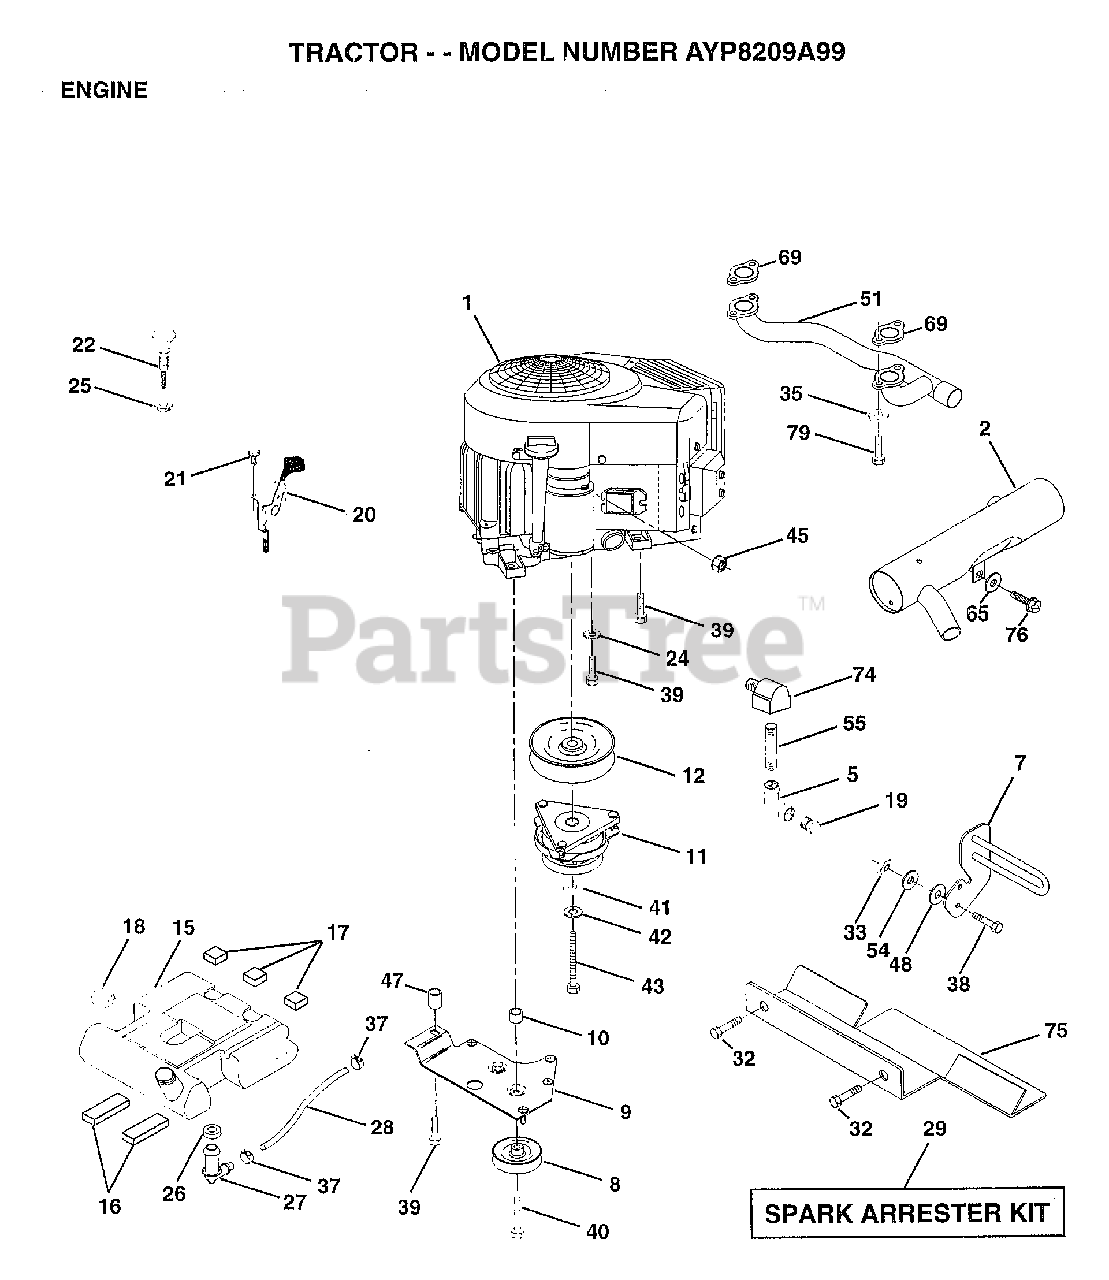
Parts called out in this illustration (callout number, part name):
2	MUFFLER.SIDE.VGT
5	ELBOW
7	GUARD.MUFFLER.ASM
9	KEEPER ASM BELT
10	BUSHING.
12	PULLEY.ENG.CLUTCH
15	TANK FUEL REAR
16	PAD IDLER TI
17	PAD-SPACER LT
18	CAP ASM FUEL
19	PLUG T
20	CONTROL.TRTL.37
21	SCREW LT
22	CHOKE CONTROL
24	LOCKWASHER
25	"NUT,KEPS 3/8-24IM"
26	BUSHING OUTLET T
27	STEM.TANK.FUEL
29	SPARK ARREST KIT
32	SCREW LT
33	NUT
35	LOCKWASHER
37	HOSE CLAMP
38	"BOLT,HEX"
39	SCREW.3/8-16X2.25
40	SCREW.TT.3/8-16X4
41	WASHER
42	LOCKWASHER
43	BOLT.7/16-20X4.25
45	NUT
47	SPACER.ENGINE
48	WASHER T
51	MANIFOLD.PIPE.VGT
54	WASHER
55	PIPE NIPPLE LT
65	WASHER
74	ELBOW STREET BASS
75	SHIELD.HEAT.INTEK.VGT
76	SCREW
79	SCREW
